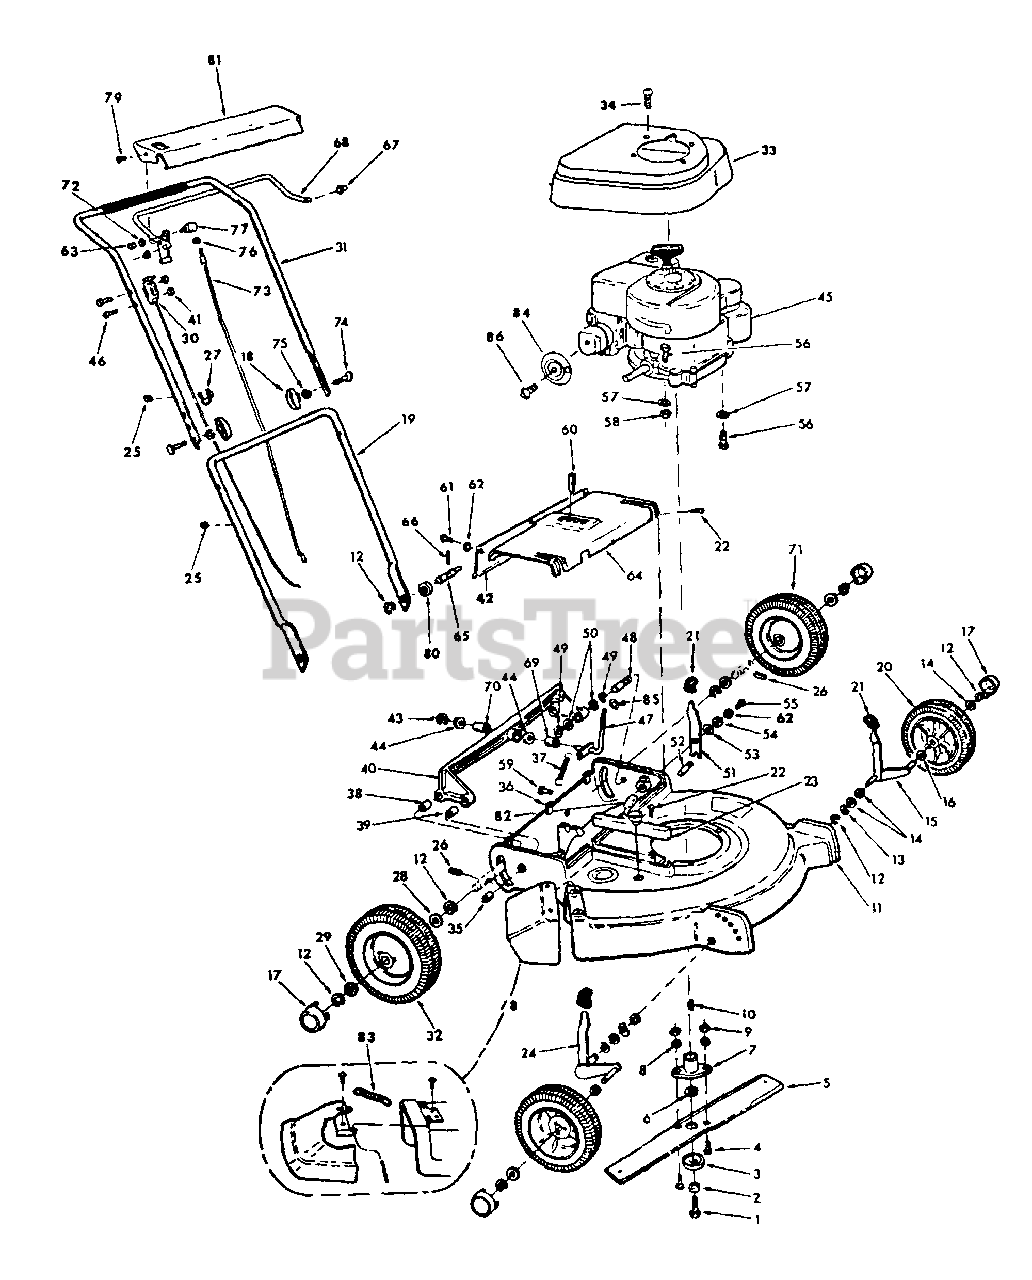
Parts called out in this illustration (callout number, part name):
1	SCREW, 3/8-24 X 1-1/8 HEX-HD CAP
2	WASHER, 3/8 REG LOCK
3	WASHER, BLADE TO CRANKSHAFT
4	SCREW, 1/4-20 X 3/4 HEX-HD CAP
5	BLADE, 22 IN
6	SPACER, ANTI FLIP BRACKET
7	ADAPTER, BLADE
8	WASHER, 1/4 REG LOCK
9	NUT, 1/4-20 HEX.
10	KEY, WOODRUFF - ENGINE CRANK
11	HOUSING ASSY, BLADE
12	RING, RETAINING
13	WASHER, WAVE
14	WASHER, 1/2 X 1 X .030
15	AXLE, FRONT LH
16	WASHER, 1/2 F 1 X .125
18	KNOB, HANDLE
19	HANDLE, LOWER
20	WHEEL AND TIRE ASSY. FRONT
21	KNOB, ADJUST LEVER
22	SCREW, 10-16 X 5/8 ZND HEX-HD MACH
23	GUARD, CHAIN
24	AXLE, FRONT RH
25	GUIDE, CABLE
26	PAWL, REAR AXLE
27	CLIP, CABLE
28	WASHER, REAR WHEEL INNER
29	WASHER, REAR WHEEL OUTER
30	CONTROL ASSY, THROTTLE
31	HANDLE, UPPER
32	WHEEL AND TIRE ASSY, RH
33	SHROUD, ENGINE
34	SCREW, 8-15 TRUSS-HD
36	NUT, U-SHAPED SPRING
37	SPRING, HEIGHT ADJUST
38	BEARING
40	BRACKET AND BEARING ASSY
41	NUT, 10-32 HEX. LOCK
42	DEFLECTOR, REAR DECK
43	RING, RETAINING
44	WASHER
45	ENGINE, 3.5 HP
46	SCREW, 10-32 X 1-3/8 HEX-HD MACH
47	LEVER AND BRACKET ASSY
48	PIN, PIVOT LH
49	RING, RETAINING
51	HANDLE, UP-STOP
52	PIN, UP-STOP
53	WASHER, RUBBER
54	SPACER, UP-STOP LEVER
55	SCREW, 10-32 X 1/2 PAN-HD
56	SCREW, 5/16-18 X 1-1/2 ZND HEX-HD CAP
57	WASHER, .344 X .625 X .054 ZND
58	NUT, 5/16-18 ZND HEX
59	PIN, 1/4 X .500 ZND CLEVIS
60	KNOB, HEIGHT ADJUST
61	SCREW, 10-16 X 5/8 ZND HEX-HD TAP
62	WASHER, NO. 10 EXT-INT LOCK
63	NUT, 10-24 HIGH CROWN
64	COVER AND PLATE ASSY
65	PIN, HANDLE PIVOT LH
66	PIN, 3/16 X 1 HV SLT SPRING
68	ROD ASSY, GRIP
71	WHEEL AND TIRE ASSY. LH
72	WASHER, .219 X .500 X .036
73	CABLE, DRIVE CONTROL
74	SCREW, 5/16-18 X 1-3/4
75	WASHER, 5/16 REG LOCK
76	NUT, 1/4-28 HEX
77	TRUNNION, CABLE
79	SCREW, 10-32 X 1/2 HEX WASHER-HD TAP
80	WASHER, 1/2 X 15/16 X .0625
81	PANEL, GRIP ROD
82	CAP, WASHOUT PORT
83	SPRING, DEFLECTOR
84	DEFLECTOR, MUFFLER
86	SCREW, 8-32 X 1-1/8 SEALS
